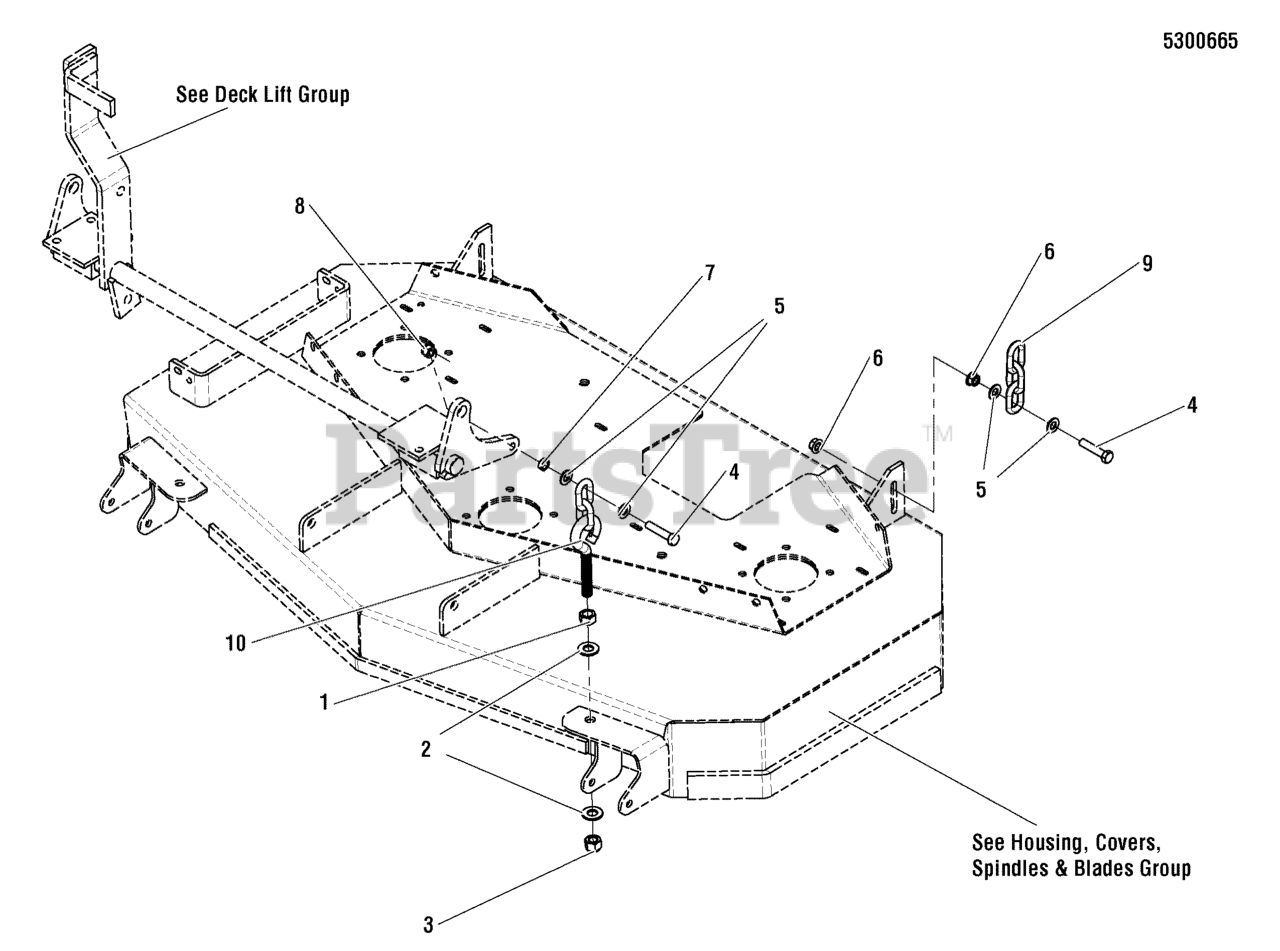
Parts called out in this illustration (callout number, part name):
1	NUT, 1/2-13 HEX
2	WASHER, 1/2 SAE
3	NUT, Hex Flange, Nylock, 1/2-13
4	BOLT, 3/8-16 X 1-3/4" GD5 CZ
5	WASHER, 3/8 SAE
6	NUT, 3/8-16 HEX SERRATED FLANGE
7	NUT, 3/8-16 HEX JAM
8	NUT, 3/8-16 HEX NYLOCK FLANGE
9	CHAIN, 5/16 GD30, 3 LINKS
10	HANGER, FRONT DECK-2LINK, 5.5" EB
